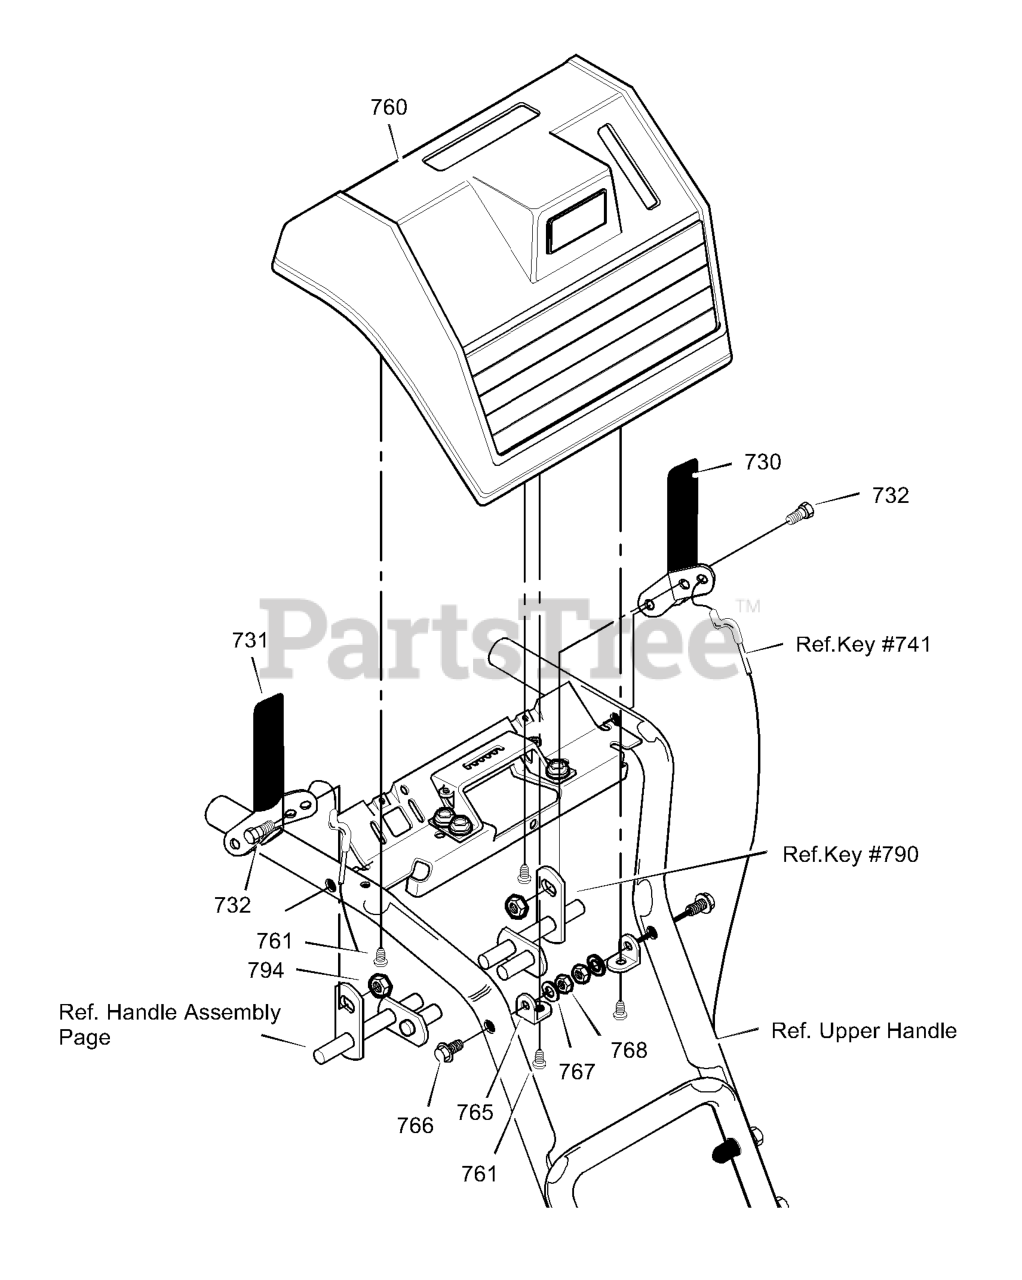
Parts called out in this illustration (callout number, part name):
730	CLUTCH HANDLE LH
731	CLUTCH HANDLE RH
732	BOLT, 1/4-20 X .50
760	PANEL, CONTROL
761	SCREW, 10 X .62
765	BRACKET, PANEL
766	SCREW, 5/16-18 x 1.75
767	WASHER, HVSPTLK
768	NUT, 5/16-18
794	NUT, 1/4-20
